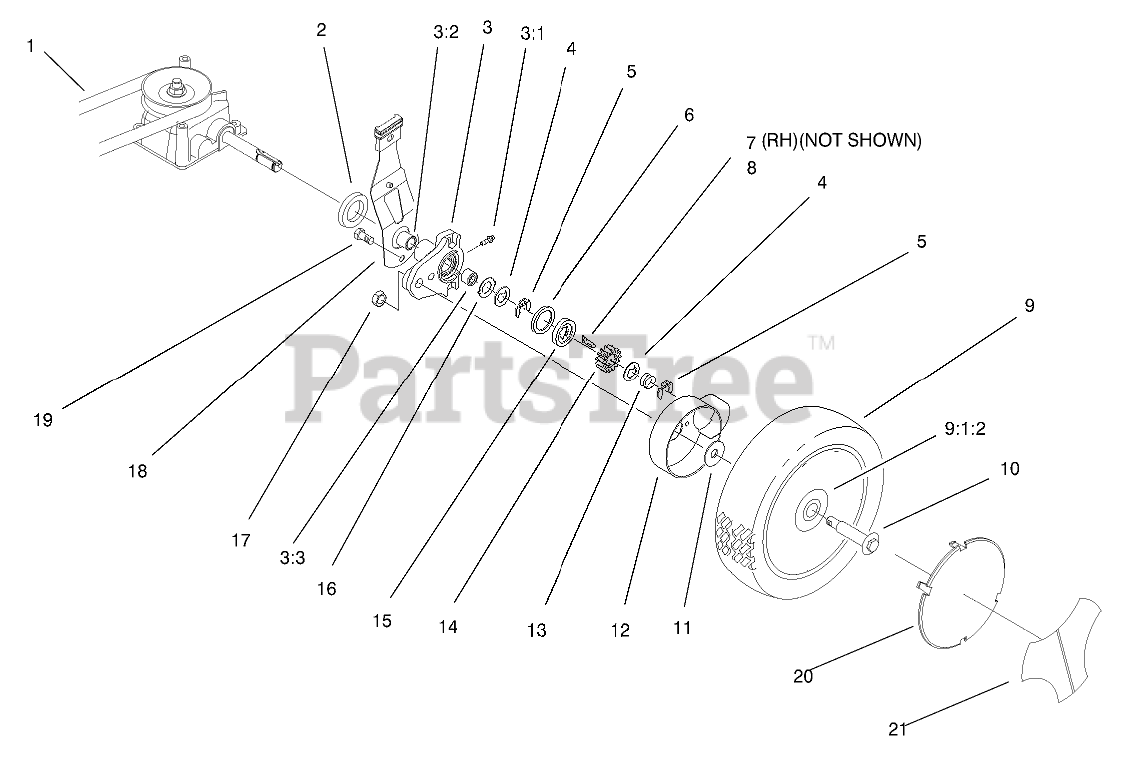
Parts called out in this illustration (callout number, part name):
1	V-BELT
2	SPACER-AXLE SHAFT
3	REAR HEIGHT ADJUSTMENT ARM ASM
3:1	FITTING-GREASE
3:2	BUSHING
3:3	BUSHING
4	WASHER-THRUST, KEYED
5	RING-CLIP, LOCKING
6	RING-FRICTION
7	KEY-ROCKING, RH
8	KEY-ROCKING, LH
9	WHEEL AND TIRE ASM
9:1	Wheel ASM
9:1:2	BUSHING
10	BOLT-SHOULDER
11	WASHER-STEPPED
12	COVER-WHEEL
13	SPRING-COMPRESSION
14	GEAR-PINION
15	WASHER-CLUTCH
16	WASHER-ARM, PIVOT
18	REAR SPRING ARM ASM
19	SCREW-HWH
20	COVER-WHEEL, SMART
21	LABEL-WHEEL, SMART
